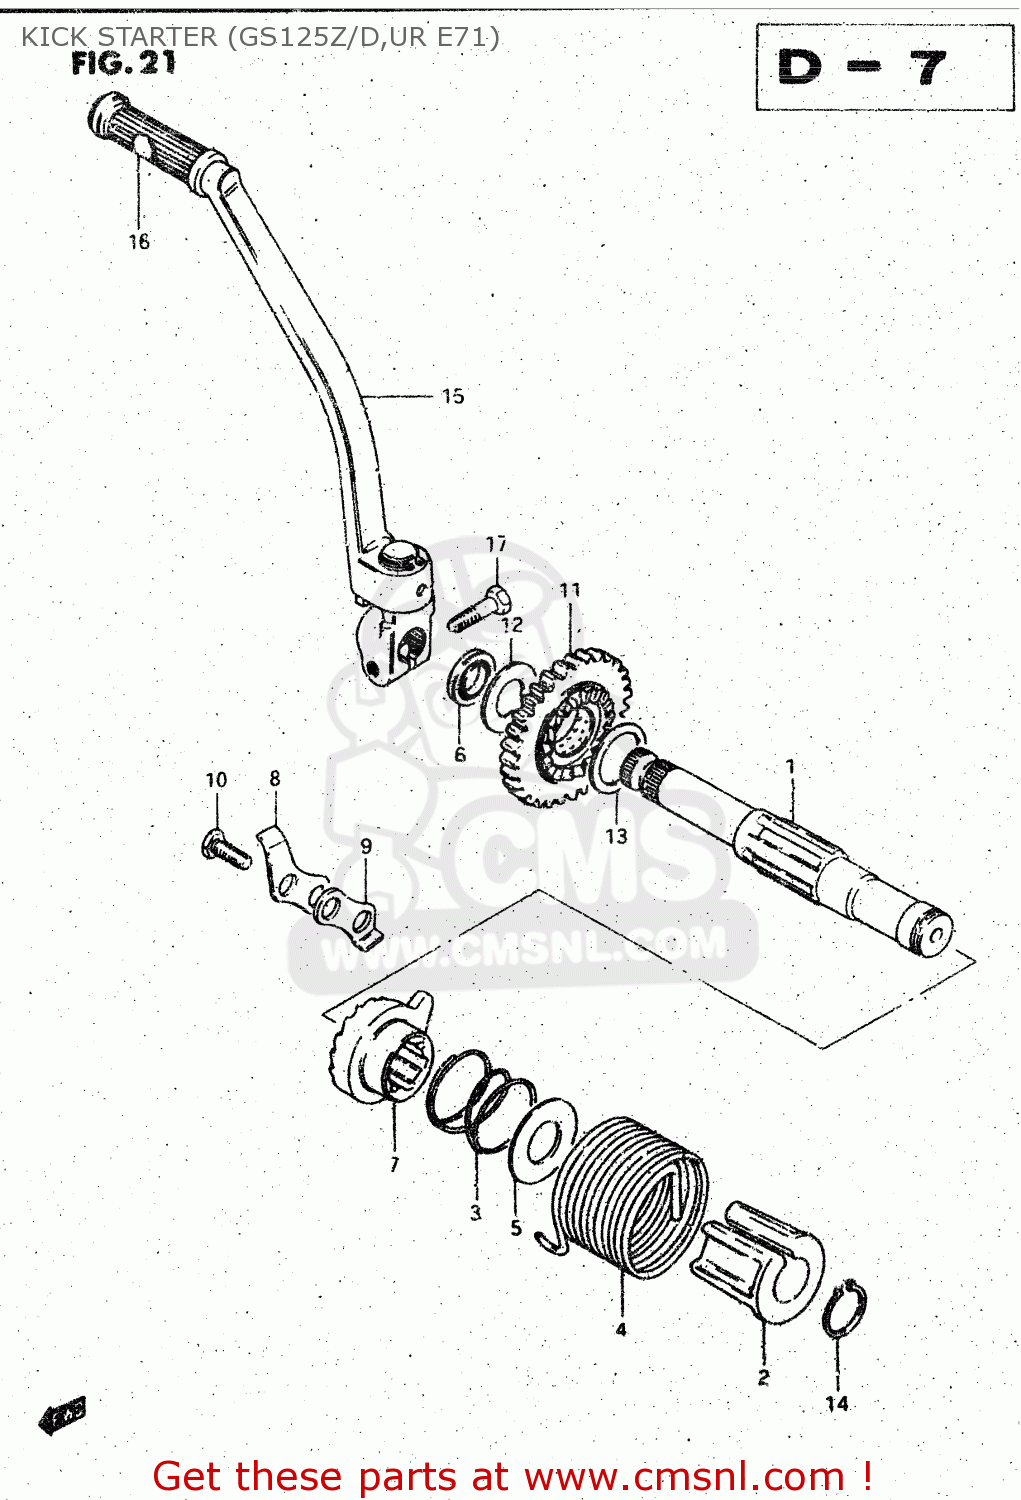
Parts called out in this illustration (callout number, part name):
1	SHAFT,KICK STARTER
2	GUIDE,KICK STARTER SFT SPRING
3	SPRING
4	SPRING
5	WASHER
6	SEAL,OIL(16X24X5)
7	STARTER,KICK
8	GUIDE,KICK STARTER
9	STOPPER,KICK STARTER
10	BOLT
11	GEAR,KICK STARTER DRIVE
12	WASHER(16X30X1)
13	WASHER
14	CIRCLIP
15	LEVER ASSY,KICK STARTER
16	RUBBER,KICK STARTER PEDAL
17	BOLT
